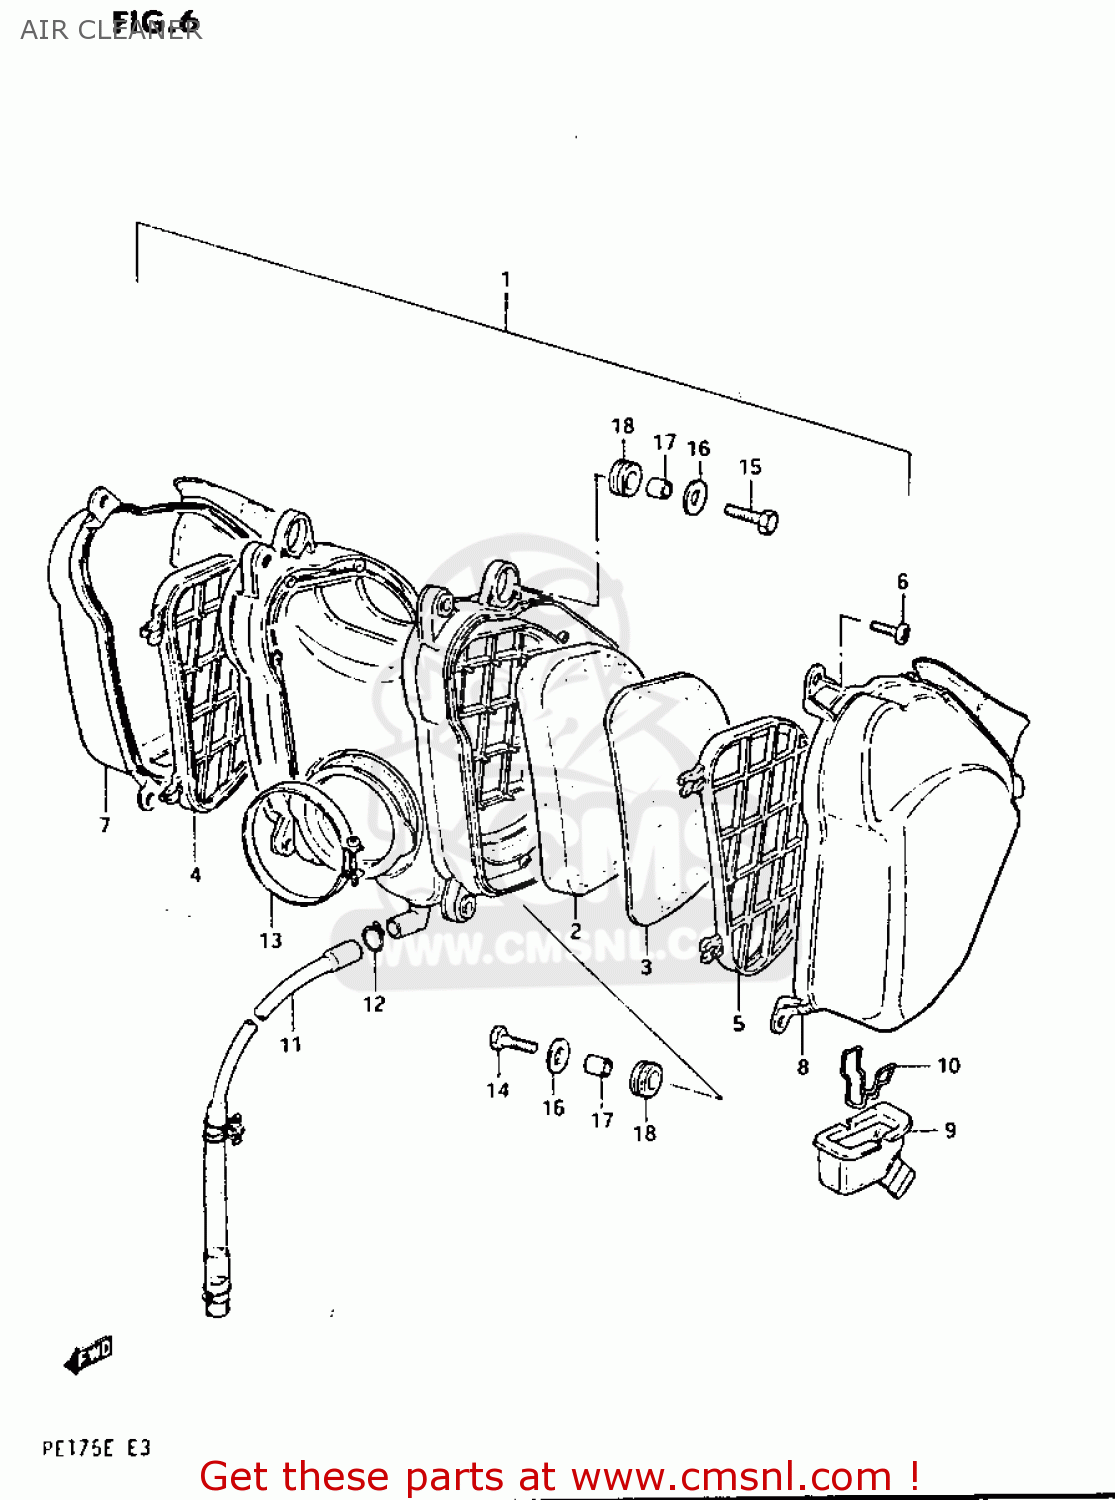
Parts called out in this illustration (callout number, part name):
1	CLEANER ASSEMBLY,AIR
2	FILTER
3	FILTER,2ND
4	HOLDER,AIR CLEANER,RIGHT
5	HOLDER,AIR CLEANER,LEFT
6	SCREW
7	CAP,AIR CLEANER,RIGHT
8	CAP,AIR CLEANER,LEFT
9	DRAIN,AIR CLEANER
10	DRAIN STOPPER
11	DRAIN TUBE
12	CLIP
13	CLAMP
14	BOLT
15	BOLT
16	WASHER(6.5X20X1.6)
17	SPACER (7X9X7)
18	CUSHION
